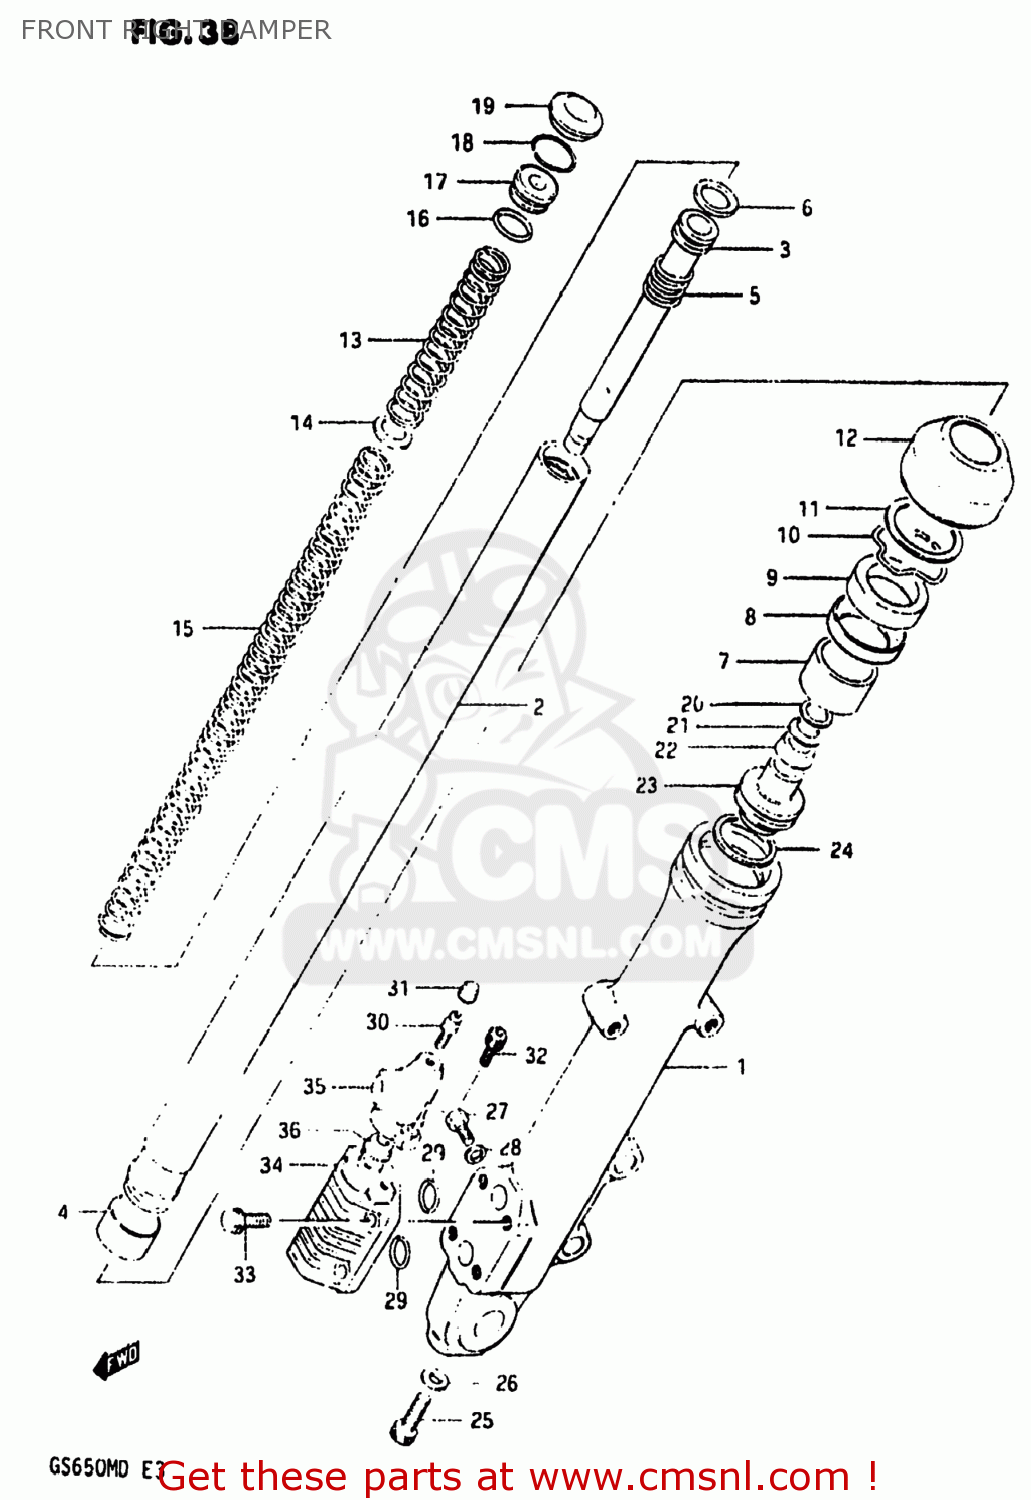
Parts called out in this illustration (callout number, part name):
1	TUBE,FORK,OUTER,RIGHT
2	TUBE,FORK,INNER
3	CYLINDER,FRONT FORK
4	PISTON
5	SPRING,FORK REBOUND
6	RING,PISTON
7	GUIDE,FORK INNER TUBE
8	SPACER,SEAL
9	OIL SEAL,FRONT FORK
10	RING,BACKUP
11	CIRCLIP,INNTERNAL
12	BOOT
13	SPRING,FRONT
14	GUIDE,SPRING
15	SPRING,FRONT FORK
16	O RING
17	SEAT,FRONT FORK SPRING
18	STOPPER RING,FORK SPRING
19	CAP,FRONT FORK
20	VALVE
21	SPRING,VALVE
22	VALVE,OIL LOCK PIEACE
23	PIECE,OIL LOCK
24	RING,PISTON
25	BOLT(8X27)
26	GASKET (NAS)
27	BOLT
28	GASKET,DRAIN,PLUG (NAS)
29	O RING,FR FORK
30	BREATHER
31	CAP
32	BOLT
33	BOLT
34	MODULATOR VALVE SET,FRONT
35	MODULATOR VALVE SET,FRONT
36	SEPARATOR,FRONT FORK MODULATOR
